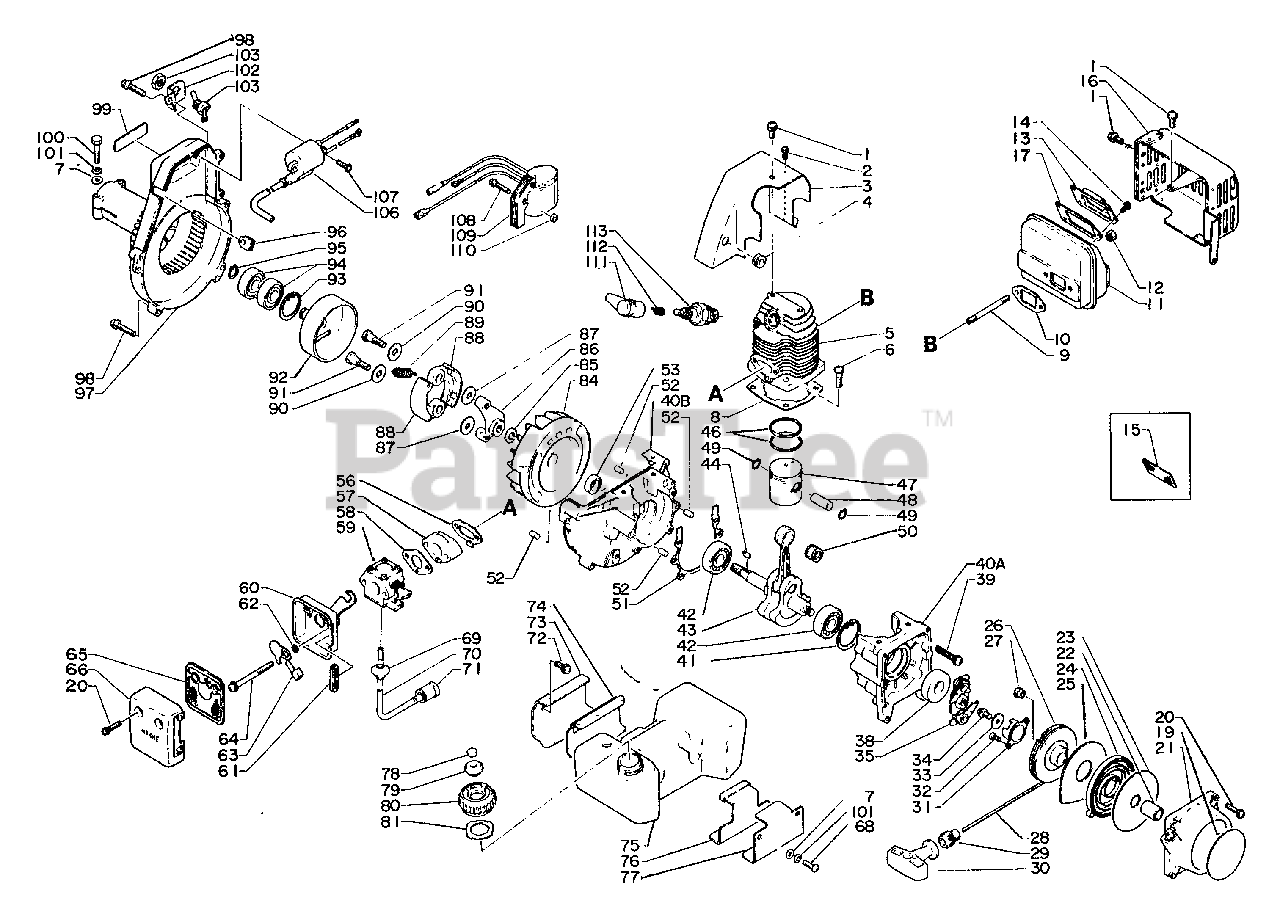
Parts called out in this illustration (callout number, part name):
1	SCREW - 5X10
2	SCREW - 4X10
3	COVER, ENGINE
5	CYLINDER
6	SCREW - 5X20
7	WASHER - 5
8	GASKET, CYLINDER
9	STUD
10	GASKET, EXHAUST
11	MUFFLER
12	LOCKNUT - 5
13	GUIDE, EXHAUST
14	SCREW - 4X8
15	SCREEN, SPARK ARRESTOR
16	COVER, MUFFLER
17	GASKET, EXHAUST
19	LABEL - ECHO
20	SCREW - 4X20
21	CASE, STARTER
23	PLATE, STARTER
24	SPRING, REWIND
25	PLATE, STARTER
26	REEL, ROPE
27	RETAINER, ROPE
28	ROPE, STARTER - 3.5X850
29	GUIDE, ROPE
30	GRIP, STARTER
31	CATCHER, PAWL
32	SCREW - 4X8
33	WASHER - 5
34	SCREW - 5X10
35	STARTER PAWL ASSY
38	SEAL, OIL
39	SCREW - 5X30
40	CRANKCASE KIT
40A	CRANKCASE KIT
40B	CRANKCASE KIT
41	RING, RETAINING - 35
42	BEARING, BALL - 6202
43	CRANKSHAFT ASSY
46	RING, PISTON
47	PISTON
48	PIN, PISTON
49	RING, RETAINING - 8
50	BEARING, NEEDLE
51	GASKET, CRANKCASE
52	PIN - LOCATING
53	SEAL, OIL
56	GASKET, INTAKE
57	INSULATOR, INTAKE
58	GASKET, INTAKE
59	CARBURETOR WA-87
60	CASE, AIR FILTER
62	WASHER - 5
63	SHUTTER, CHOKE
64	SCREW - 5X60
65	FILTER, AIR
66	COVER, AIR FILTER
68	SCREW - 5X14
70	PIPE - 3X5X150 -- BLACK
71	FILTER, FUEL
72	SCREW - 5X14
73	BRACKET, FUEL TANK
74	CUSHION
75	TANK, FUEL
76	CUSHION
77	BRACKET, FUEL TANK
80	CAP
81	GASKET, CAP
84	FLYWHEEL
85	LOCKWASHER - 8
86	HUB, CLUTCH
87	WASHER - 6
88	SHOE, CLUTCH
89	SPRING, CLUTCH
91	BOLT, CLUTCH
92	DRUM, CLUTCH
93	RING, RETAINING - 32
94	BEARING, BALL - 6201
95	RING, RETAINING - 12
97	CASE, FAN
98	SCREW - 5X25
99	LABEL - MODEL
100	BOLT - 5X25
101	LOCKWASHER - 5
102	BRACKET, SWITCH
103	IGNITION SWITCH KIT
106	COIL, IGNITION
107	SCREW - 4X15
108	SCREW - 4X22
109	COIL, IGNITION
111	CAP, SPARK PLUG
112	TERMINAL, SPARK PLUG CAP
113	SPARK PLUG -- BM-6A
